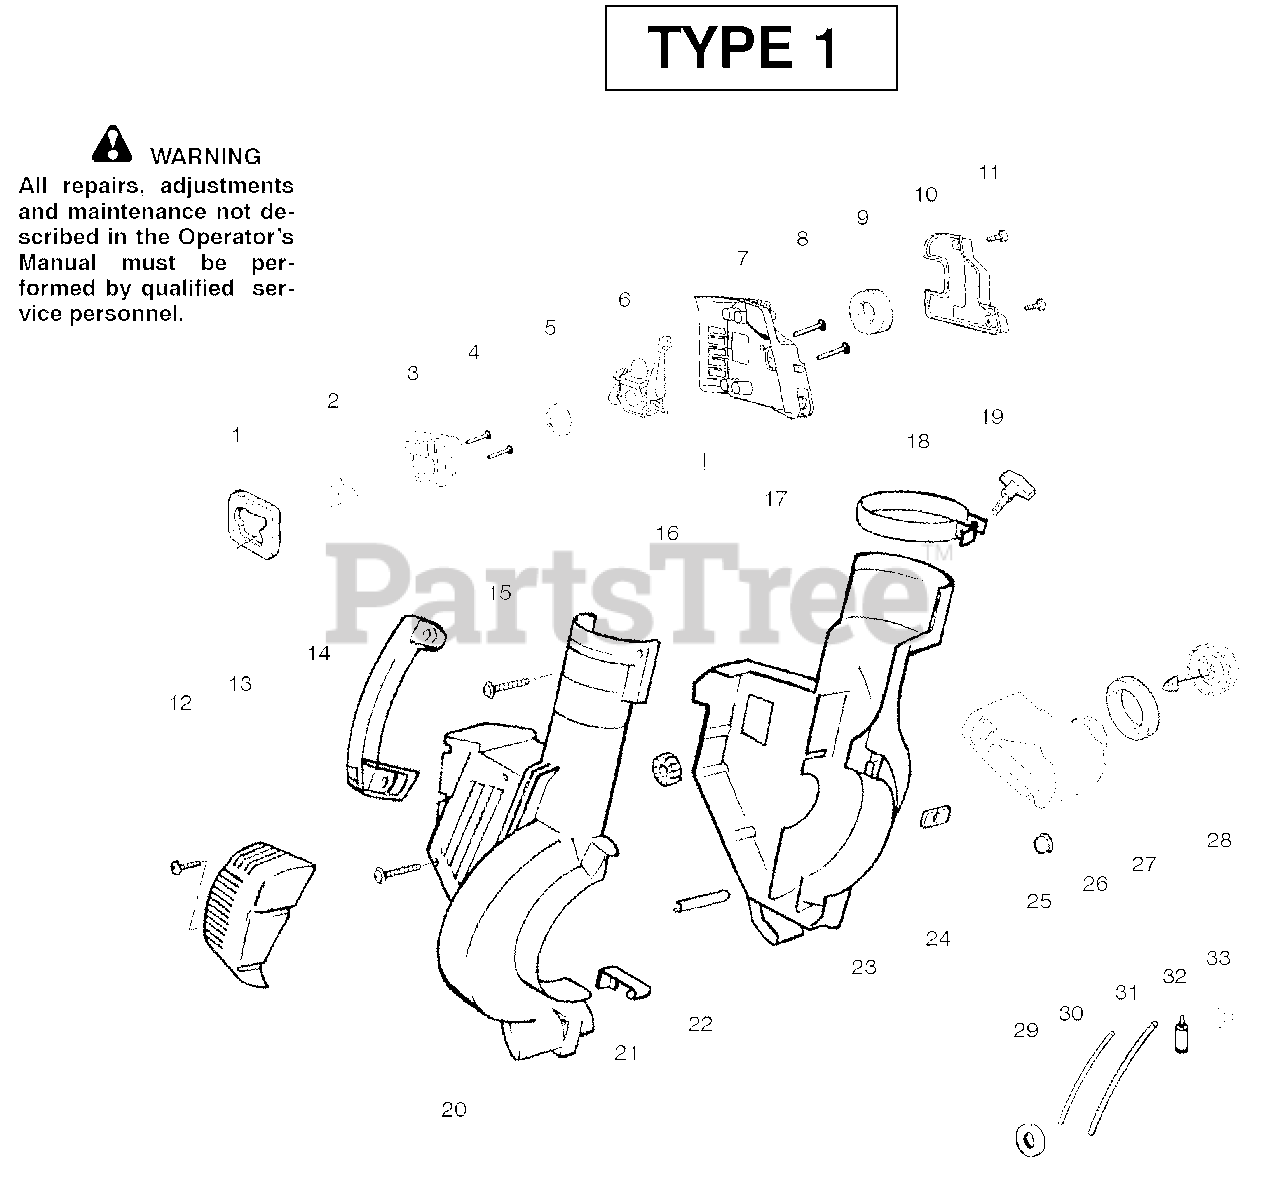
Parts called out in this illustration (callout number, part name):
1	Air Dam (kit)
2	Gasket-Adapter (kit)
3	Carburetor Adaptor
5	Gasket-Carburetor (kit)
6	Kit-Carb Ass'y. (C1Q-W11)
10	Cover-Air Filter
11	Screw-Air Box Cover
13	Assy-Muffler Cover
16	Isolator-Handle
17	Foam 25.4mm (kit)
18	Clamp-Blower Tube
19	Knob-Tube Clamp
20	Housing-Right
21	Spring-Cover Latch
22	Guide-Starter Rope
25	Isolator-Crankcase
26	Assy-Fuel Tank
27	Gasket-Fuel Tank
28	Fuel Cap w/Retainer
29	Grommet-Shroud
30	Kit-Line Carb/Purge
31	Kit-Line Tank/Purge
32	Assy-Fuel Pick-up
33	Grommet-Fuel line (kit)
